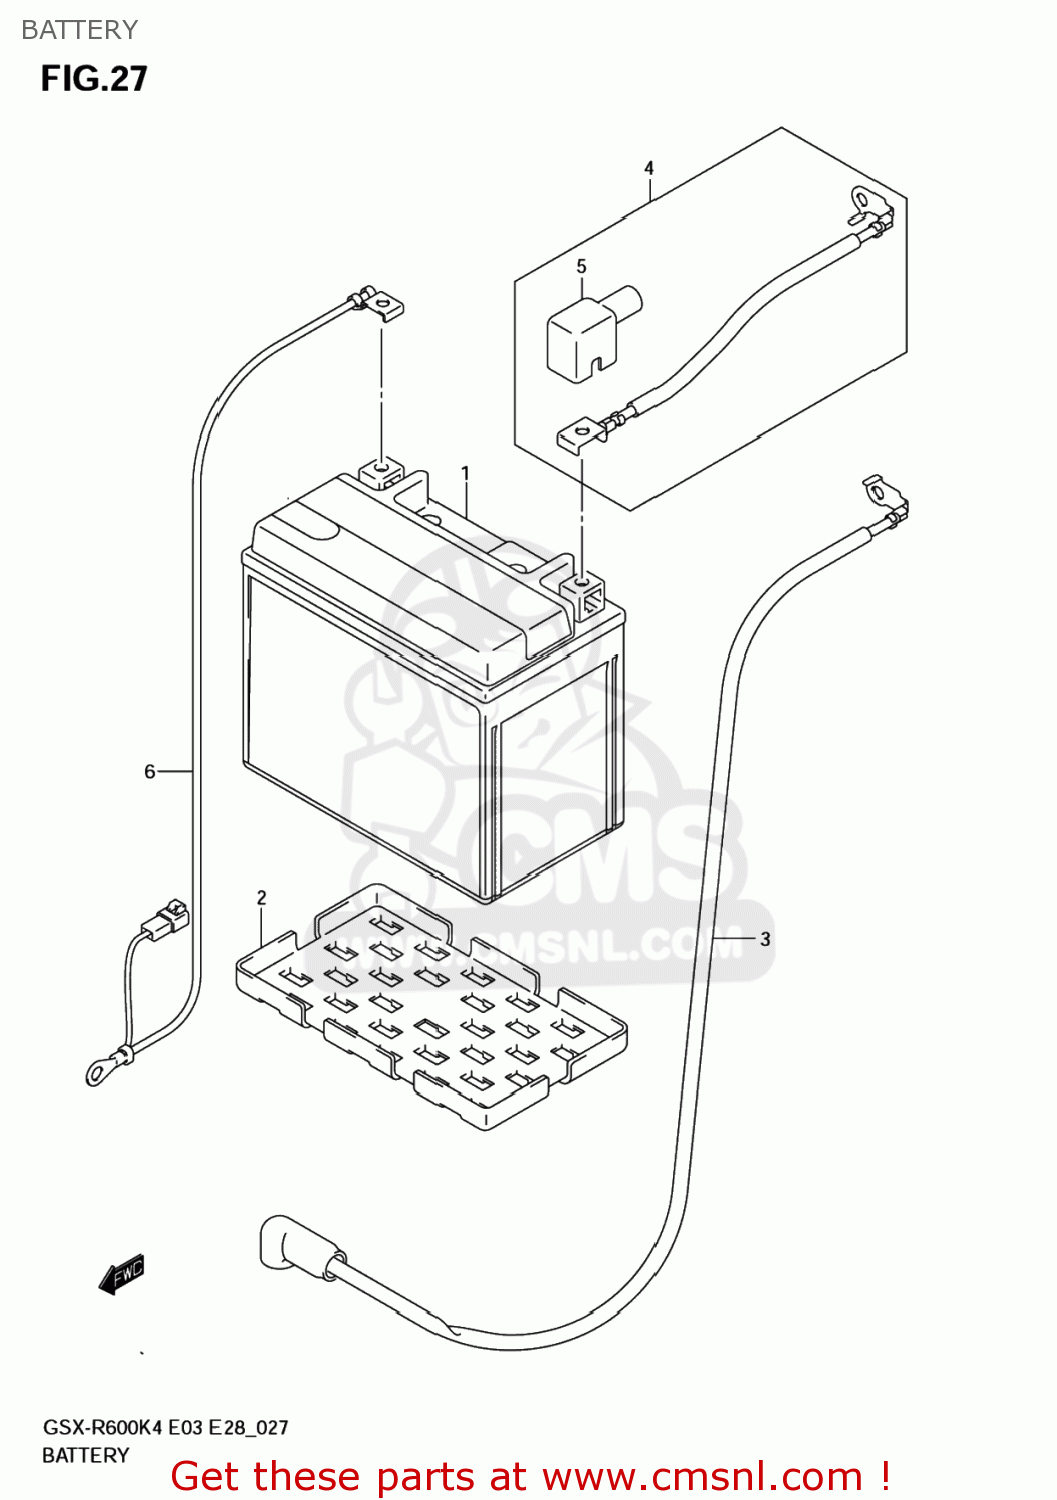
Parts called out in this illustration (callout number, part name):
1	BATTERY ASSEMBLY (12V) FTX
2	PROTECTOR,BATTERY
3	WIRE,STARTER MOTOR LEAD
4	WIRE,BATTERY PLUS LEAD
5	CAP,BATTERY PLUS
6	WIRE,BATTERY MINUS LEAD
